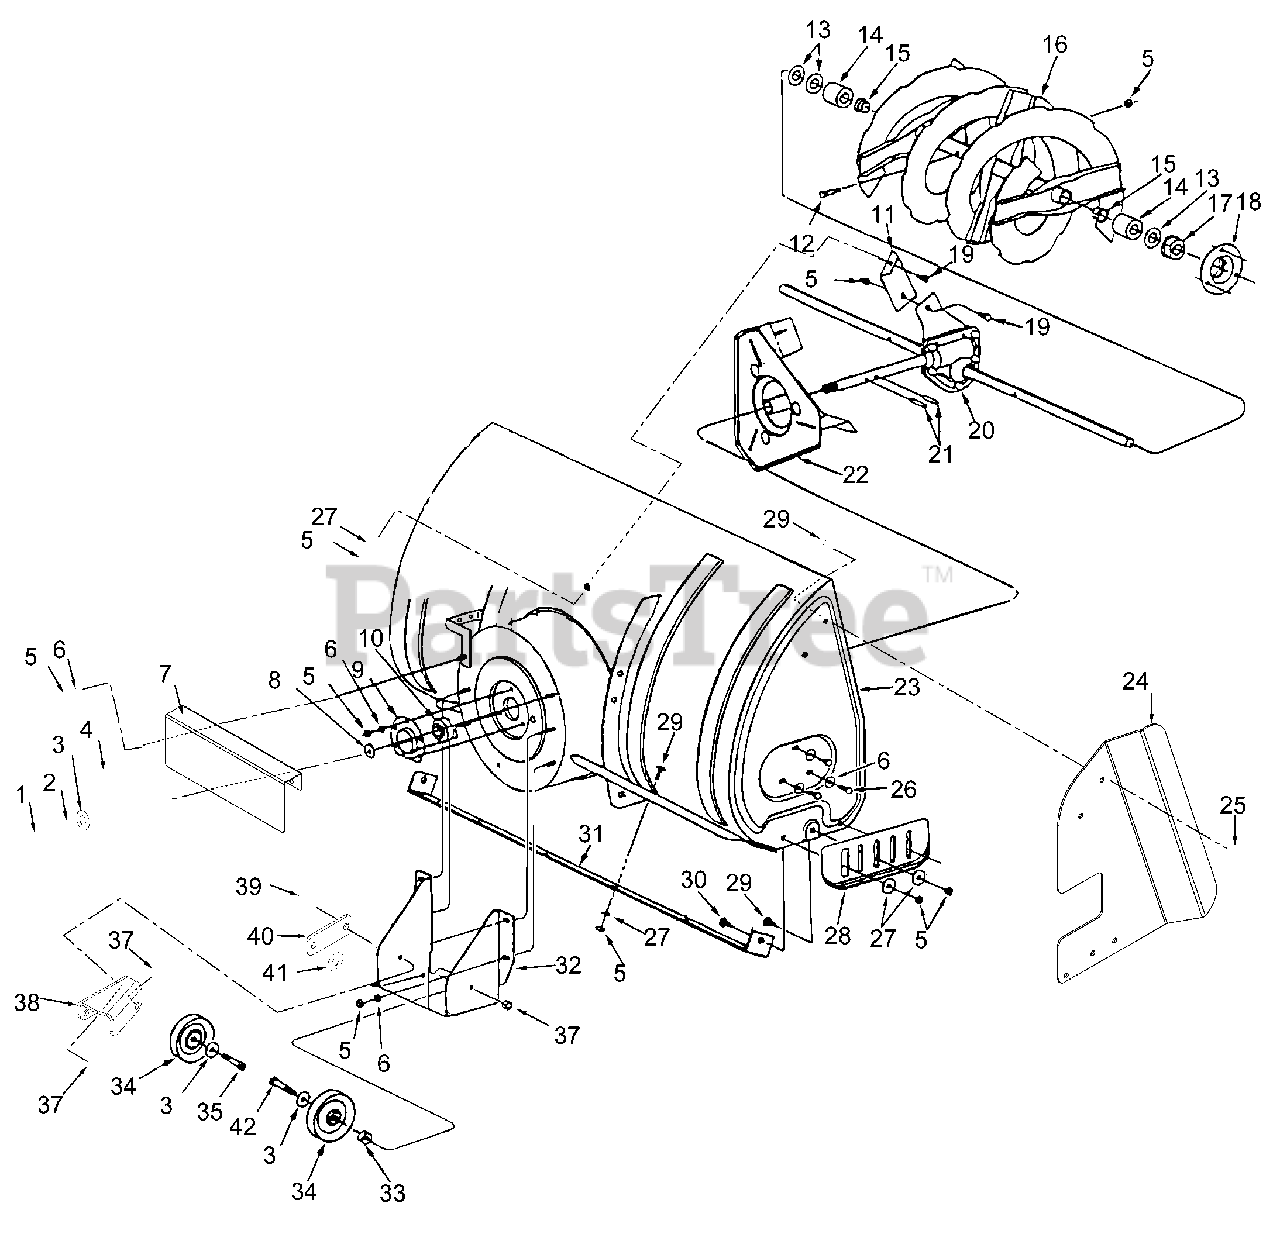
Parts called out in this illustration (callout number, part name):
1	Hex Bolt, 3/8-24 X 1
2	Lock Washer, 3/8
4	Pulley, V-Type
5	Hex Lock Nut, 5/16-18
6	Lock Washer 5/16
7	Finger Guard
9	Housing, Bearing
10	Bearing, Ball
11	Bracket, Housing Brace
12	Bolt, Shear 5/16-18 x 1-1/2
13	Washer, .76 x 1.49 x .06
14	Spacer, .75 ID x 1.25 OD x .51
15	Bearing, Split, 3/4
16	Spiral Assembly, R.H.
17	Bearing Flange
18	Housing, Bearing
19	Hex Bolt, 5/16"-18 x 3/4"
20	Gear Assembly
21	Spiral Pin, 1/4 x 1-1/2"
22	Impeller Assembly
23	Housing Assembly
24	Drift Cutter, Right Hand
25	Nut-Locking-Top-Flange .31-18
26	Bolt, Self-Tap 5/16 x 3/4"
27	Washer, 5/16
28	Skid Shoe
29	Carriage Bolt, 5/16-18 x 3/4
30	Carriage Bolt, 5/16-18 x 1
31	Scraper Plate
32	Bracket, Idler
33	Bushing
34	Pulley, V-Type
35	Bolt-Hex .38-16 X 1.50 Grade 5
37	Nut-Locking-Top-Flange .38-16
38	Bracket
39	Bolt-Hex .38-16 X 1.00 Grade 5
40	Plate, Shim
41	Washer-Flat-Steel .406 x 1.00 x.188
42	Bolt-Hex .38-16 X 2.00 Grade 5
NA	Drift Cutter, Left Hand
NA	(Gravely Part Number)
